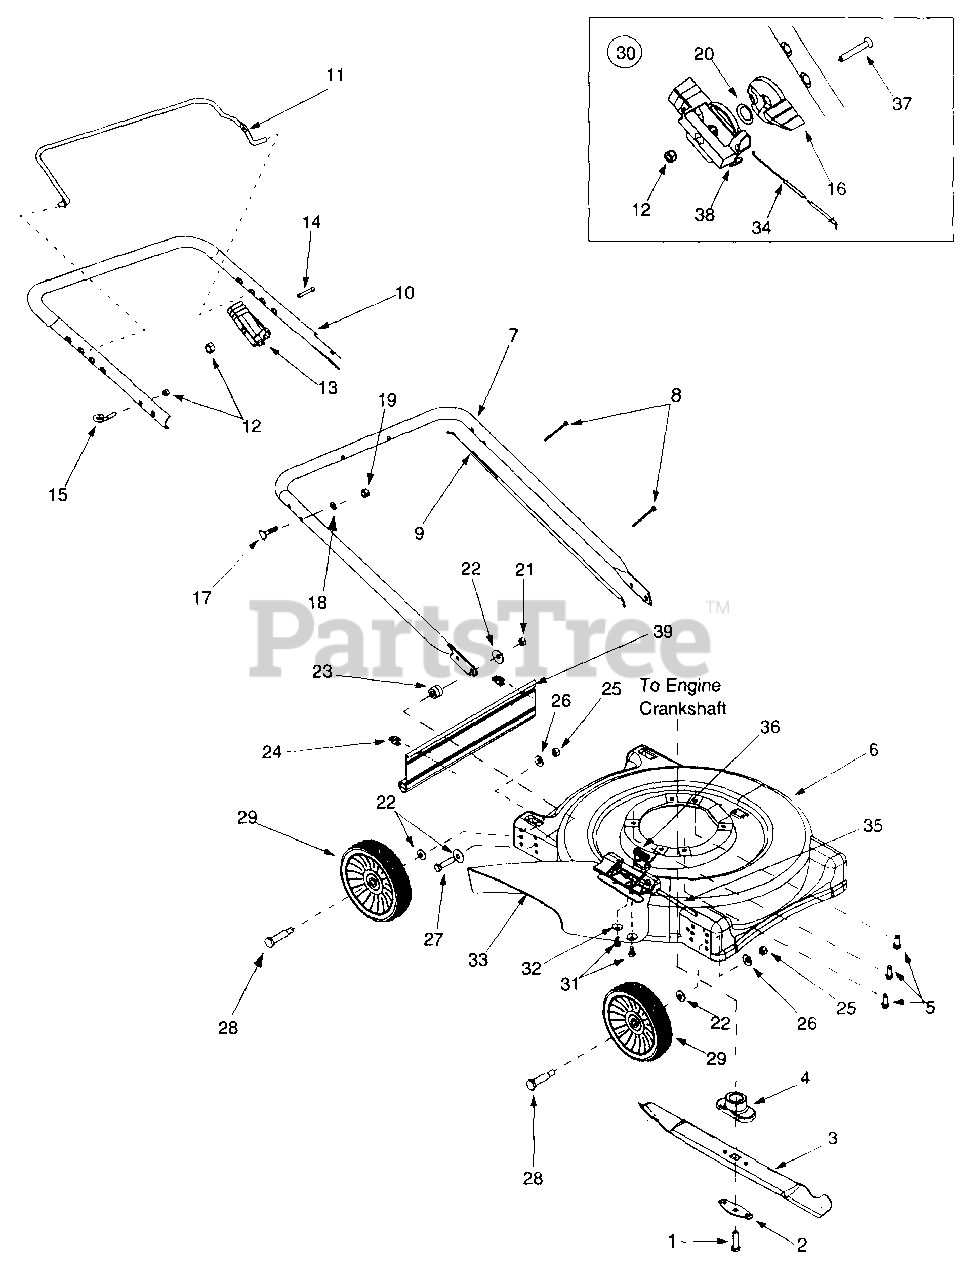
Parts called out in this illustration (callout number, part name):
1	Hex Bolt 3/8-24 x 1.5" Lg.
2	Support, Bell-Blade
3	22" Blade, Std.
4	Adaptor, Blade
5	Screw: TTSems, 3/8 - 16 x 1"
8	Cable Tie
9	Control Cable-43"
12	Hex L-Nut 1/4-20 Thd.
13	Control Cable Box
14	Oval C-Sunk Scr.
15	Rope Guide
16	Throttle Lever
17	Curved Carr. Bolt 5/16-18 x 1" Lg.
18	L-Wash. 5/16" I.D.
19	Hex Nut 5/16-18 Thd.
20	Spring Washer
21	Hex L-Nut 3/8-24 Thd.
22	Bell Washer .380 ID x .88"
23	Spacer .391" I.D. x .375" Lg.
24	Hinge Clip
25	Hex Nut 3/8-16
26	Bell Washer .39 I.D. x 1.13
27	Hex Bolt 3/8-24 x 1.5
28	Axle Bolt
29	Wheel Assy
30	Throttle Box Complete
31	Hex Self-Tap Scr. 1/4-20 x .5"
32	Bell-Wash. 1/4" I.D.
33	Chute Deflector Ass'y
34	Throttle Cable, 51"
35	Hinge Pin
36	Torsion Spring
37	Oval C-Sunk Scr.
38	Throttle Body
39	Rear Trail Shield
